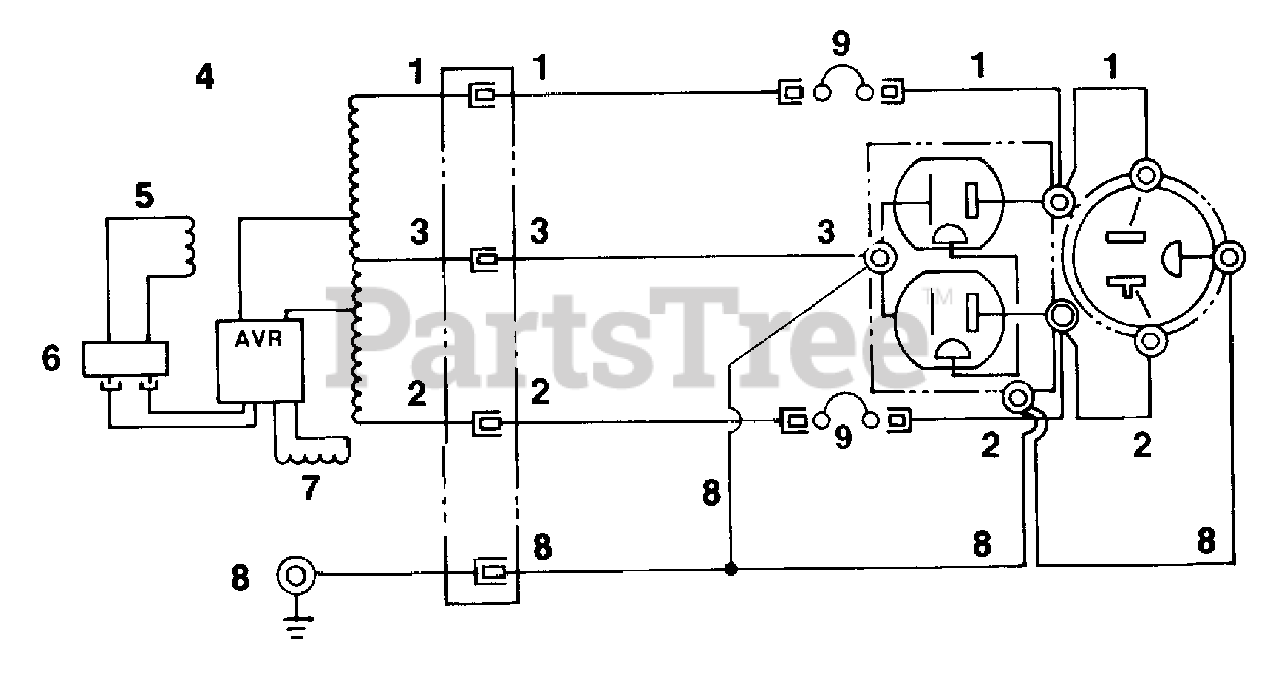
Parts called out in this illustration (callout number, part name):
1	Red
2	Blue
3	White
4	Main Coil
5	Field Coil
6	Brush Holder
7	Exiter Coil
8	Ground
9	Circuit Protector
